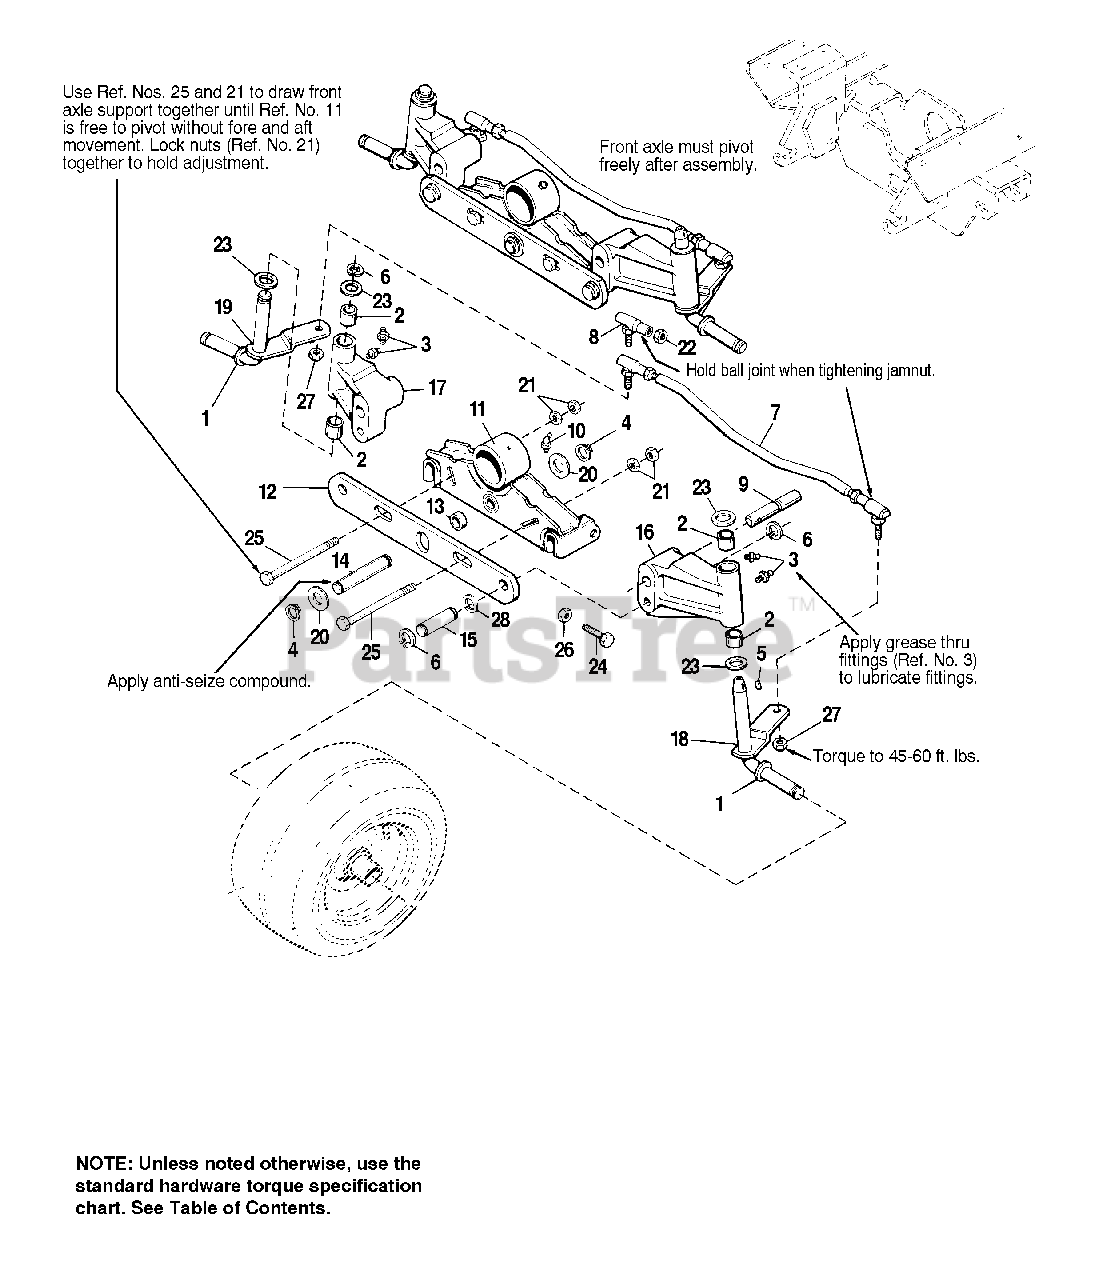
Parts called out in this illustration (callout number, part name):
1	COLLAR, Seal, Spindle Assy.
2	BUSHING, Spindle
3	FITTING, Lube, 1/4-28
4	RING, Retaining, 3/4 I.D.
5	KEY, Hi-Pro, 1/4 x 3/4
6	RING, Retainer
7	TIE ROD ASSY.
8	BALL JOINT ASSY.
9	PIN, Axle Pivot
10	FITTING, Lube, 45°, 1/4 , Drive Type
11	HITCH SUPPORT ASSY.
15	PIN, Axle Pivot
16	AXLE PIVOT ASSY., LH
17	AXLE PIVOT ASSY., RH
18	SPINDLE ASSY., LH
19	SPINDLE ASSY., RH
20	WASHER, 3/4 I.D.
21	NUT, Hex, 3/8-16
22	NUT, Hex, Jam, 1/2-20
23	WASHER, 1-1/32 x 1-5/8 x 1/16
24	CAPSCREW, Hex Hd., 5/16-18 x 1-3/4, Gr. 5
25	CAPSCREW, Hex Hd., 3/8-16 x 4
26	NUT, Hex, Centerlock, 5/16-18
27	NUT, Hex, Centerlock, 1/2-20
28	WASHER, 1-1/32 x 1-3/4 x 7 Ga.
